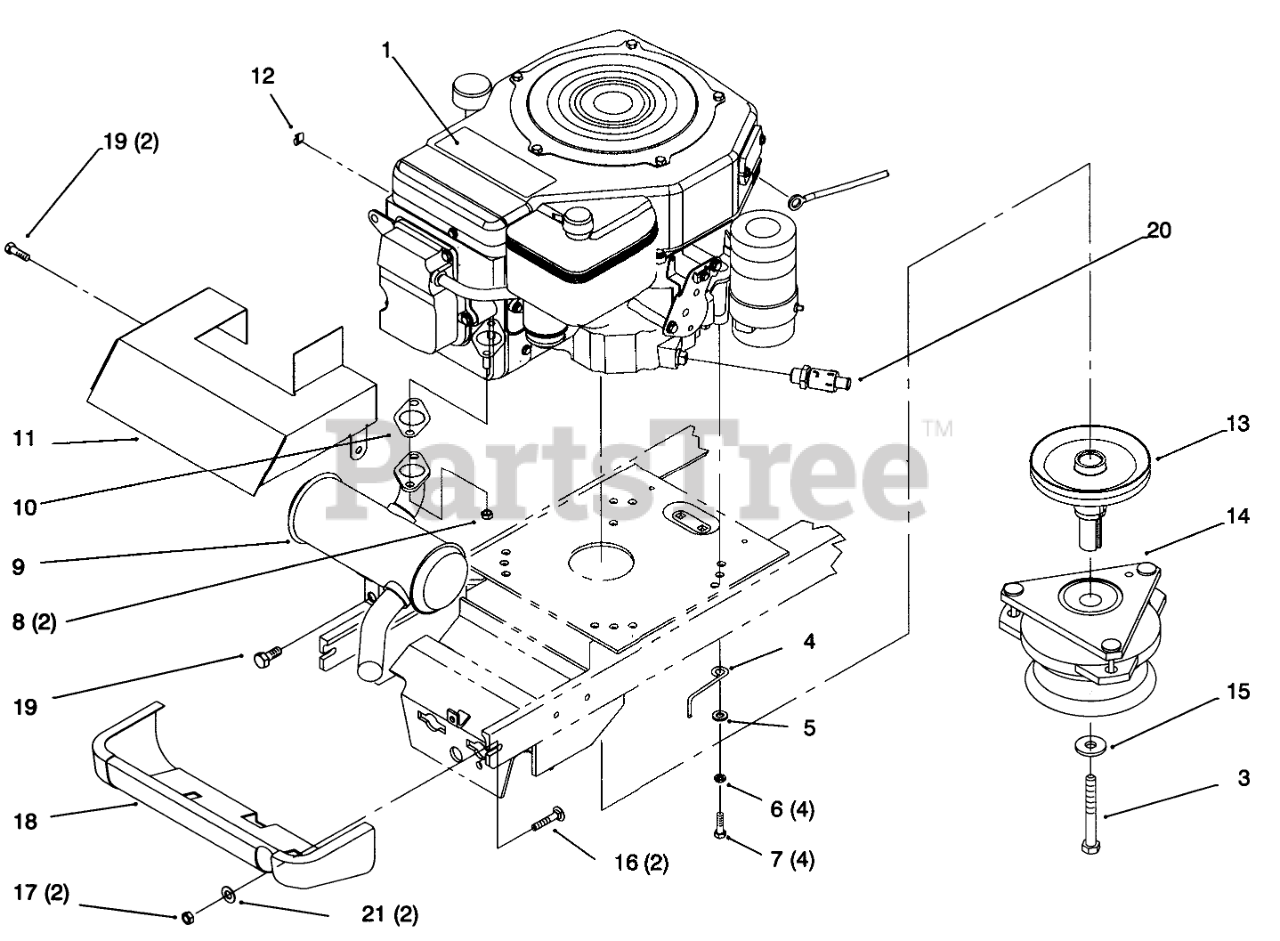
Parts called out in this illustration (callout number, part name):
1	Decal-Toro Power Plus 14 (Only On: 72042, 72043, 72062, 72063)
3	Screw-HH (Only On: 72042, 72043, 72062, 72063)
4	Guide-Belt (Only On: 72042, 72062)
5	Washer-Flat (Only On: 72042, 72062)
6	Washer-Lock (Only On: 72042, 72043, 72062, 72063)
7	Screw-HH (Only On: 72042, 72043, 72062, 72063)
8	Nut-HHF (Only On: 72042, 72043, 72062, 72063)
9	Muffler (Only On: 72042, 72043, 72062, 72063)
10	Gasket-Exhaust (Only On: 72042, 72043, 72062, 72063)
11	Baffle-Muffler (Only On: 72042, 72043, 72062, 72063)
12	Clip-Wire Retainer (Only On: 72042, 72043, 72062, 72063)
13	Pulley (Only On: 72043, 72063)
13	Pulley-Engine (Only On: 72042, 72062)
14	Clutch-PTO (Only On: 72042, 72043, 72062, 72063)
15	Washer-PTO (Only On: 72042, 72043, 72062, 72063)
16	Bolt-CARR (Only On: 72042, 72043, 72062, 72063)
17	Nut-Lock (Only On: 72042, 72043, 72062, 72063)
18	Shield-Muffler (Only On: 72042, 72043, 72062, 72063)
19	Screw-HWHTF (Only On: 72042, 72043, 72062, 72063)
20	Valve-Oil Drain (Only On: 72042, 72043, 72062, 72063)
21	Washer-Flat (Only On: 72042, 72043, 72062, 72063)
